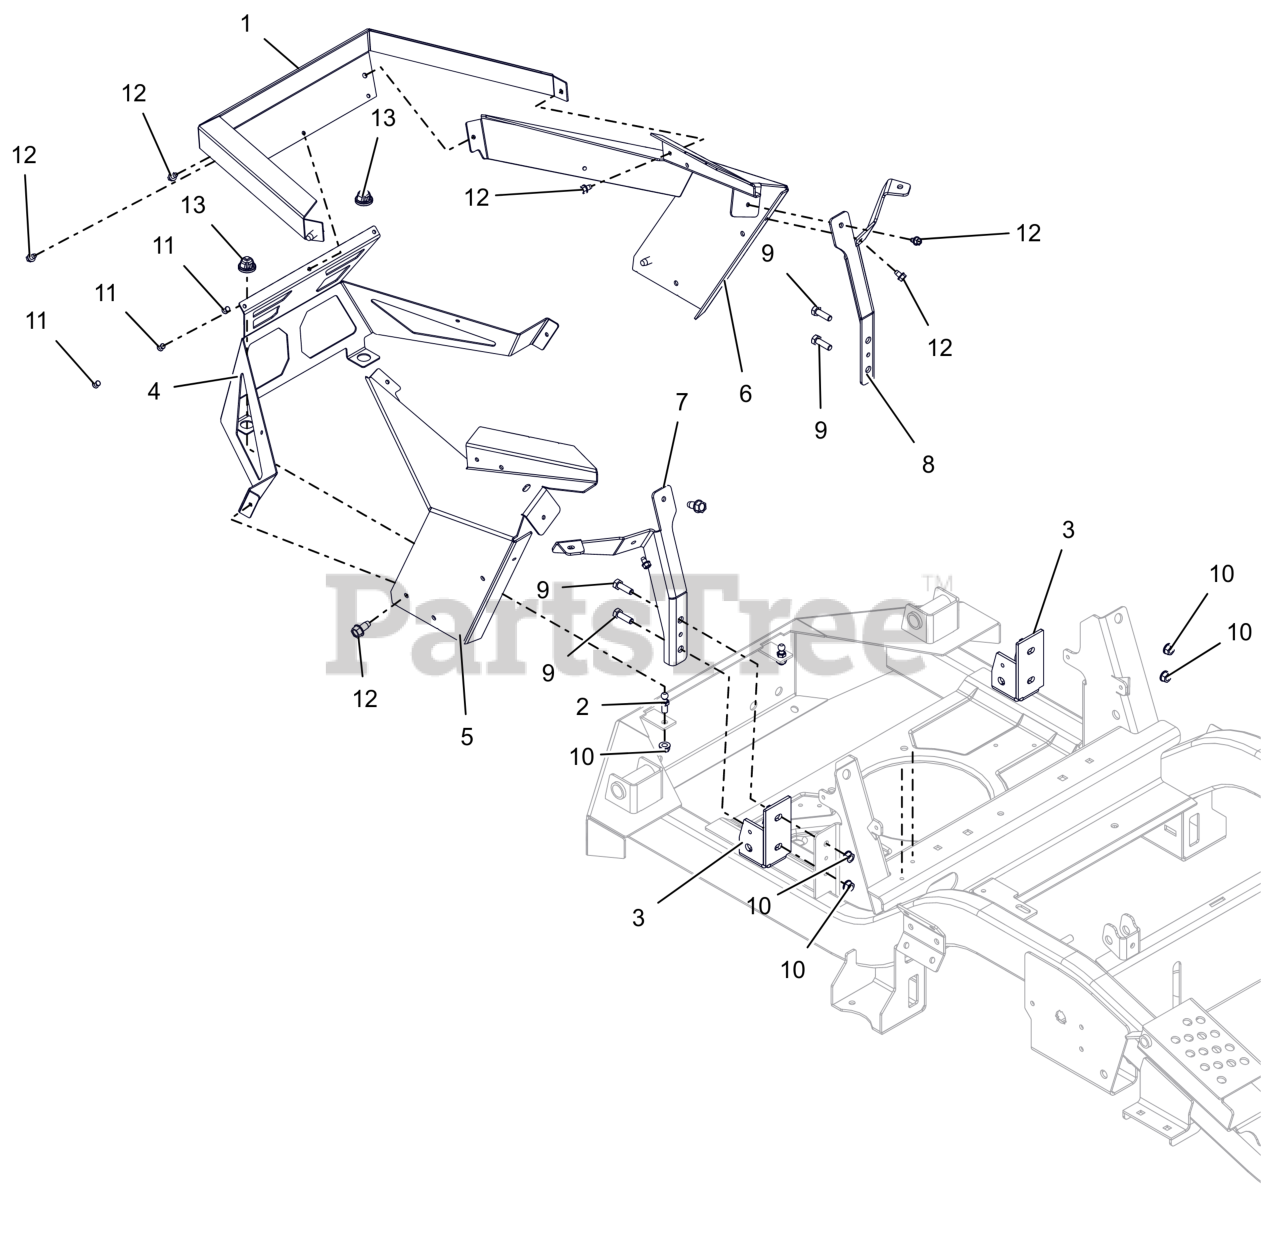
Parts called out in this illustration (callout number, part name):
1	GUARD,ENGINE WRAP
2	STUD- BALL
3	BRKT, ROPS SUPPORT (BLACK)
4	GUARD, ENGINE
5	PANEL, RH REAR FENDER MOUNT
6	PANEL, LH REAR FENDER MOUNT
7	BRKT, RH FENDER MTG (ORANGE)
8	BRKT, LH FENDER MOUNT (ORANGE)
9	BLT, HEX .31-18X1.00 G8 ZCC
10	NUT,LK-CTR-FLG .31-18 GF ZCC
11	RIVET, .1875 AL/AL .126-.250
12	SCR-TAP .
13	GROMMET, 10MM BOLLHOFF
